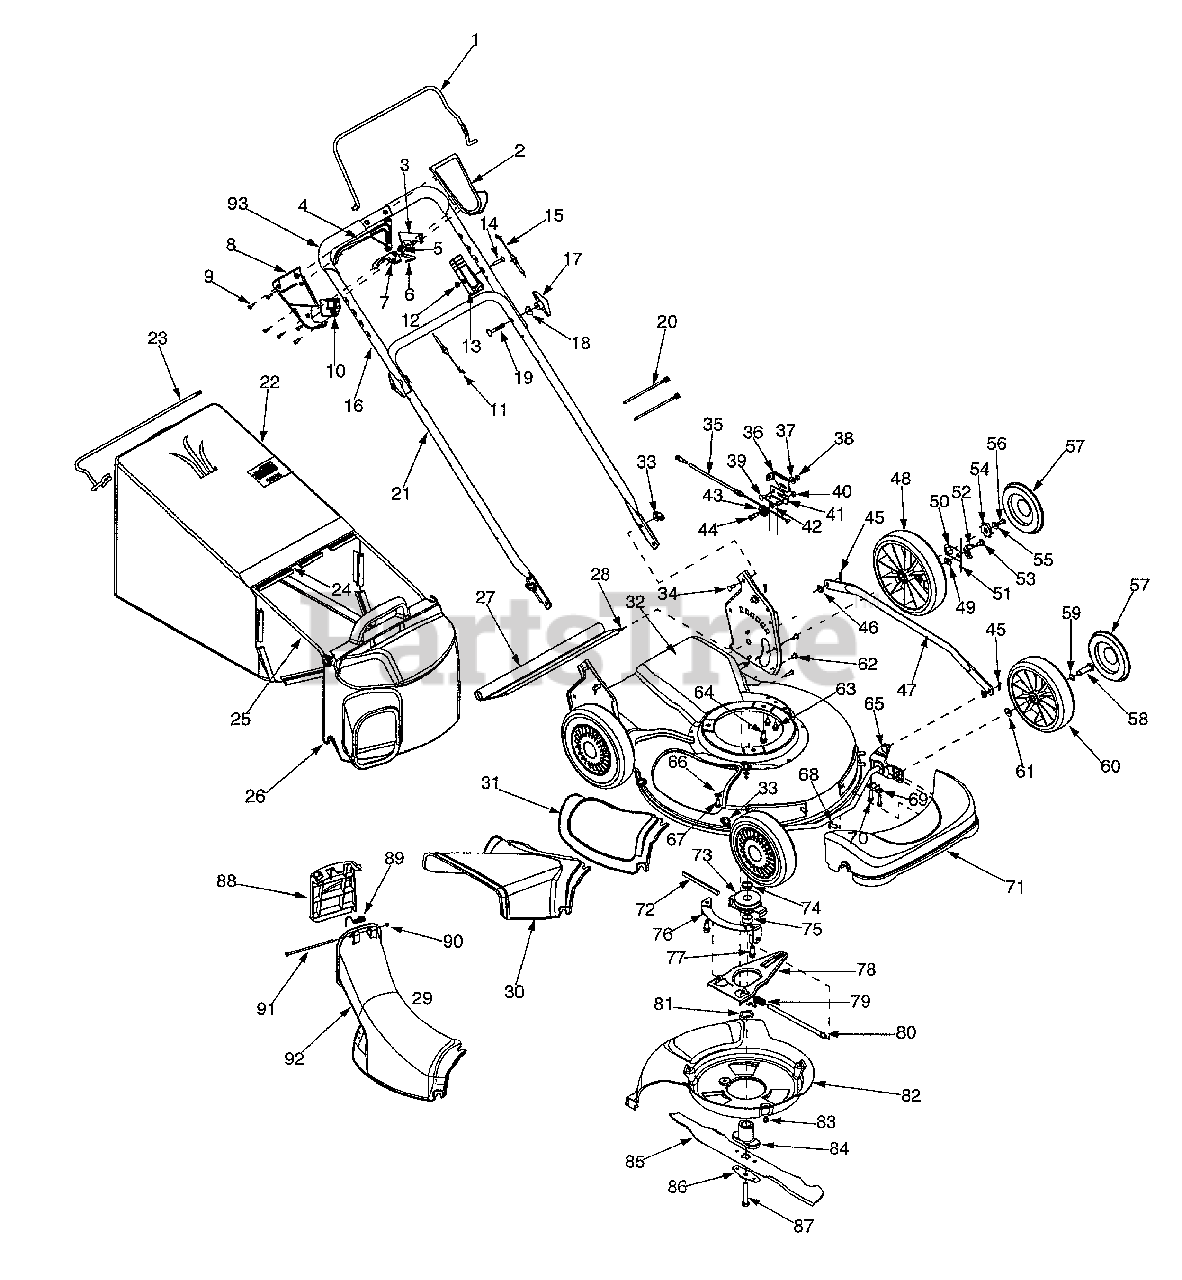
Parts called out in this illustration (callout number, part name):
1	Control Handle
2	Upper Control Handle
3	6 Spd. Rack Cable Bracket
4	Control Lever
5	Gear Insert
6	Shift Lever Spring
7	6 Speed Shift Lever
8	Lower Control Housing
9	C Sunk Tap Screw #10 x .75 Lg
10	Cable Mounting Cap
11	Drive Cable 51.0
12	Top Lock Nut 1/4-20
13	Control Housing
14	Oval C-Sunk Screw
15	Control Cable 46"
16	Upper Handle
17	Wing Nut
18	Saddle Washer.320 ID x .830 OD i
19	Carriage Bolt 5/16-18 x 2.0
20	Cable Tie
22	Grassbag
23	Support Rod w/ Rope Guide
24	Pivot Rod
25	Grassbag Frame
26	Grassbag Cover
27	Trail Shield
28	Trail Shield Wire
29	Chute Assembly
30	Side Discharge Chute
31	Mulch Cover
33	Wing Nut
34	Carriage Bolt 1/4-20 x .75
35	6 Speed Cable
36	Cable Adjustment Bracket
37	Bell Washer.265 ID x .75 OD
38	Hex Nut 1/4-20
39	Carriage Screw 1/4-20 x .50
40	Hex Nut 1 /4-28
41	Cable Mounting Bracket
42	Lock Washer 1/4
43	Roller Cable
44	Shoulder Screw.375 ID x 1/4-14
45	Cotter Pin
46	Bowed Washer
47	Single Lever Control Arm
48	Wheel 9 x 2
49	Top Lock Tab Weld Nut 1/4-20
50	Ratchet Pawl Plate
51	Plastic Spring Ratchet
52	Pawl RH
53	Shld Screw.340 ID x .285 OD
54	Wheel Rachet
55	Bell Washer.265 ID x .75 OD
56	Hex Cap Screw 1 /4-20 x .620
57	Hubcap
58	Shoulder Screw.498 x 1.445
59	Wave Washer .510 ID x .750 OD
60	Wheel 8 x 2
61	Spring Washer.401 ID x .870 OD
62	Screw 1/4-14 x .500
63	Screw 1 /4-14 x .625
64	Hex Washer Screw 3/8-16 x 1.0
65	Front Axle Assembly
66	Flat Washer.344 ID x .62 OD
67	Carriage Screw 1/4-20 x .75
68	Torx Screw
69	Block Bushing
70	Hex Washer Screw
71	Front Axle Cover
72	Belt 3/8 x 39.24
73	Pulley Assembly
74	Sleeve Spacer.88 ID x 1.13 OD
75	Sleeve Spacer.88 ID x 1.00 OD
77	Screw 3/8-18 x 1.0
80	Pivot Shaft
81	Wave Washer 1.38 ID x .88 OD
83	Screw 1/4-20 x 3.75
84	Blade Adapter Kit
85	21" Mulching Blade
86	Blade Bell Support
87	Hex Bolt 3/8-24 x 2.5
88	Chute Door
89	Torsion Spring
90	Push Cap
91	Pivot Rod
92	Discharge Chute
93	Grip
